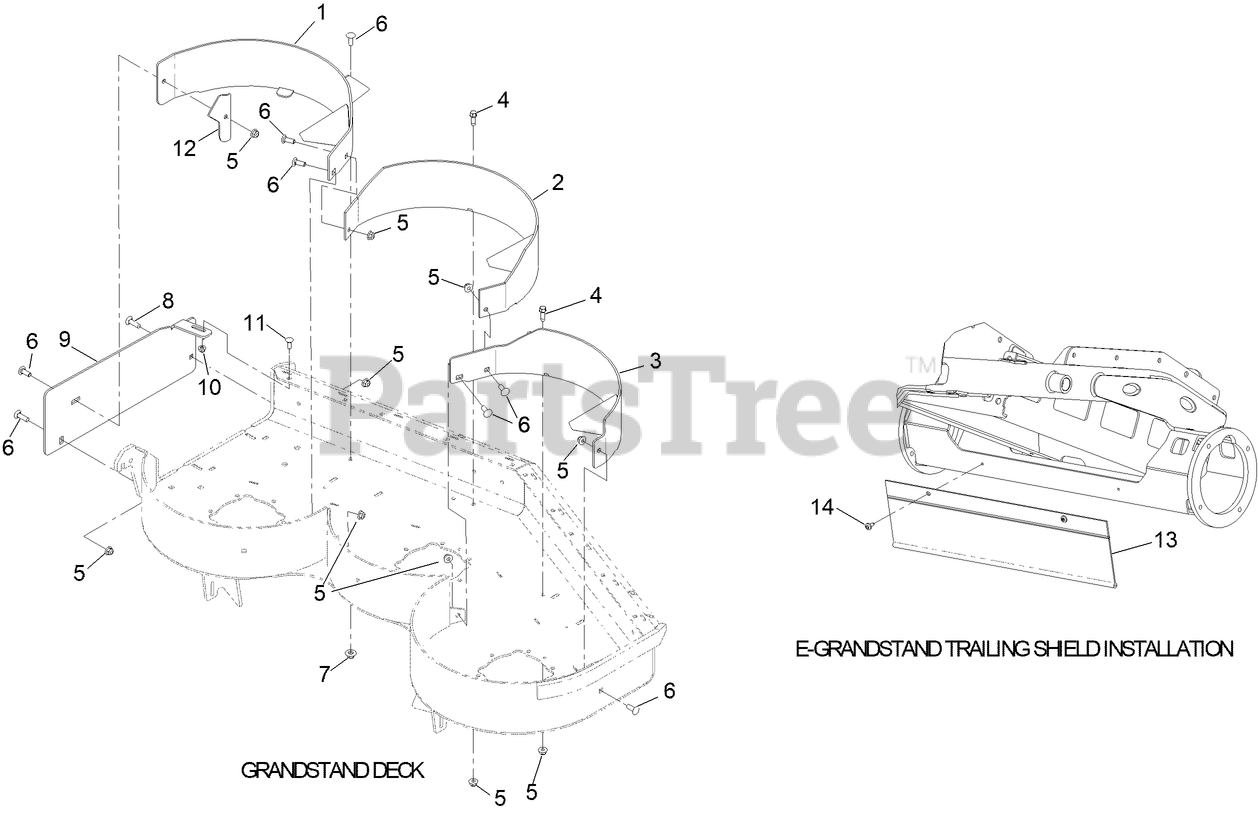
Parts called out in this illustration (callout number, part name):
1	BAFFLE ASM-RH, 52
2	BAFFLE-CENTER
3	BAFFLE-LH
5	NUT-HF, NI
6	SCREW-CARR
7	NUT-FLANGE, NI
8	SCREW-CARR
9	PLATE-COVER, DISCHARGE
10	NUT-HF, NI
11	SCREW-CARR
12	PLATE-SIDE COVER
13	SHIELD-TRAILING
14	SCREW-SHOULDER
